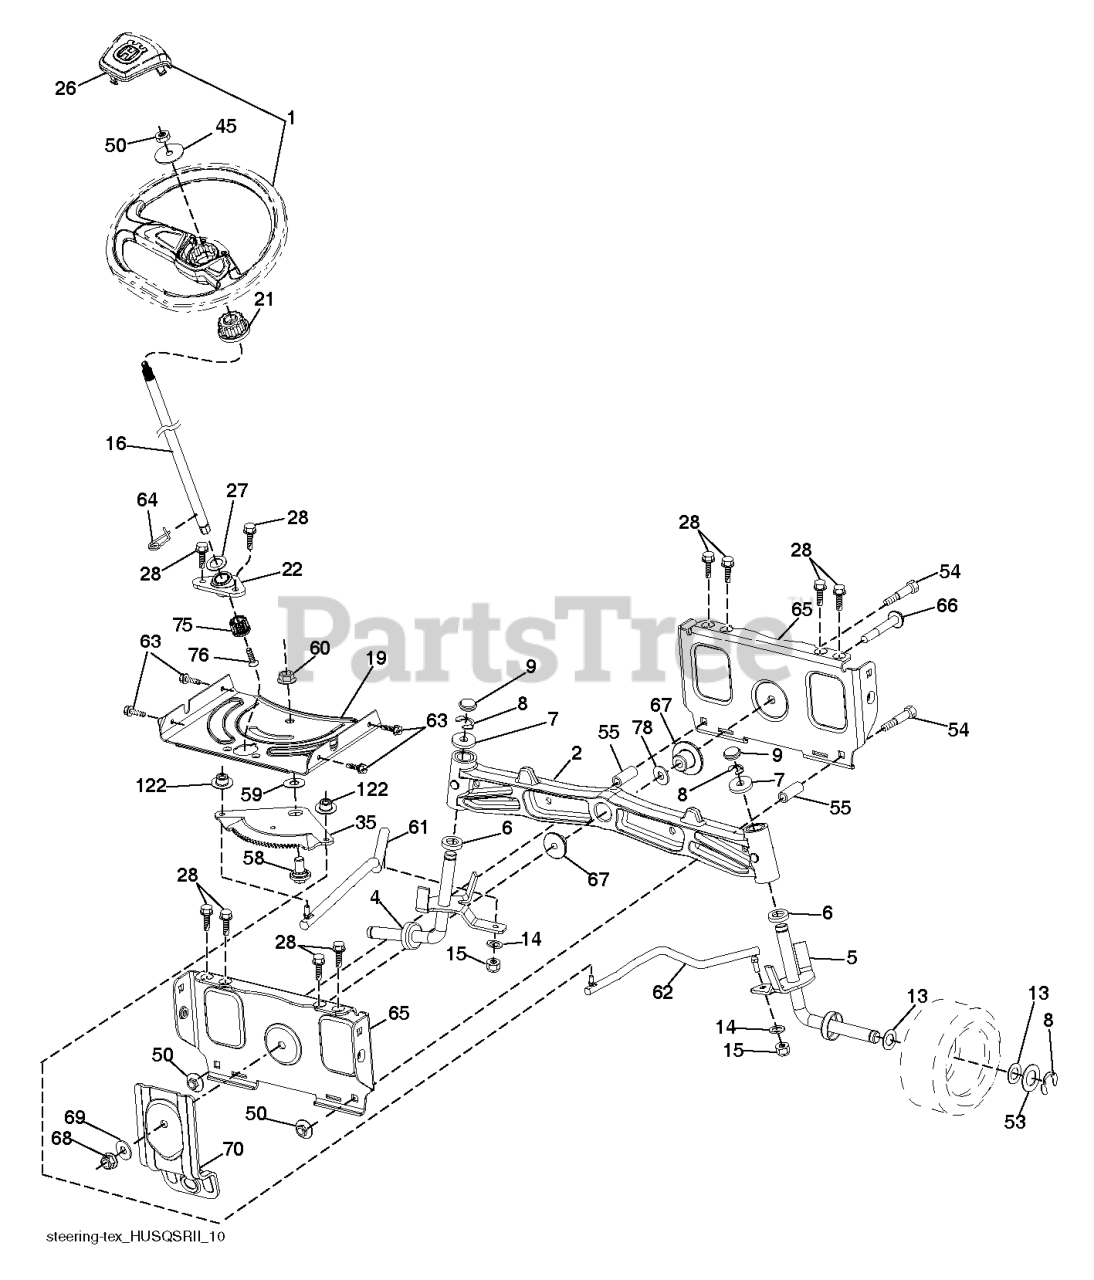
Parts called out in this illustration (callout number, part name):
1	Service Kit
2	AXLE.CAST.IRON
4	SPINDLE.WELDED.LH.16"TEX
5	SPINDLE.WELDED.RH.16"TEX
6	WASHER THRUST
9	CAP.SPINDLE.BLACK
15	NUT CROWNLOCK 3/8-24
16	SHAFT.STEER.2HIGH.SPLND.PLATED
19	PLATE.STEER.DDL.NLT/NG
21	ADAPTER.WHEEL.STEER.SPLND.ALUM
22	BEARING.SUBASM.SHAFT.STEER.LOW
28	SCREW, 3/8-16X3/4
35	GEAR.SECTOR.PLATE.DDL.
45	WASHER.3/8ID.2-3/8OD.12GA.PLTD
50	NUT LOCK FLG 3/8-16 UNC
53	WASHER.HARDENED
55	SPACER.BRACE.AXLE
58	BOLT.SHOULDER.SECTOR.P
59	WASHER.THURST.SECTOR.S
60	NUT FLANGE LOCK 5/8-11
61	Links
62	Links
63	SCREW
64	RETAINER.CLIP.SPRING.S
65	BRACE.AXLE.FRONT.NLT/N
66	BOLT HEX FGHD 7/16-14 X 3 SERR
67	BUSHING.PM.FRONT AXLE
68	NUT.LOCK.FLANGE.7/16
69	WASHER.1.5X.505X.118
70	BRACKET.FRT.DECK.SUSP.RR.MT431
75	PINION.ZINC PLATED
76	SCREW HEAD SOCKET LRVB
78	THRUST WASHER
122	CAP.GEAR.SECTOR.TEX
